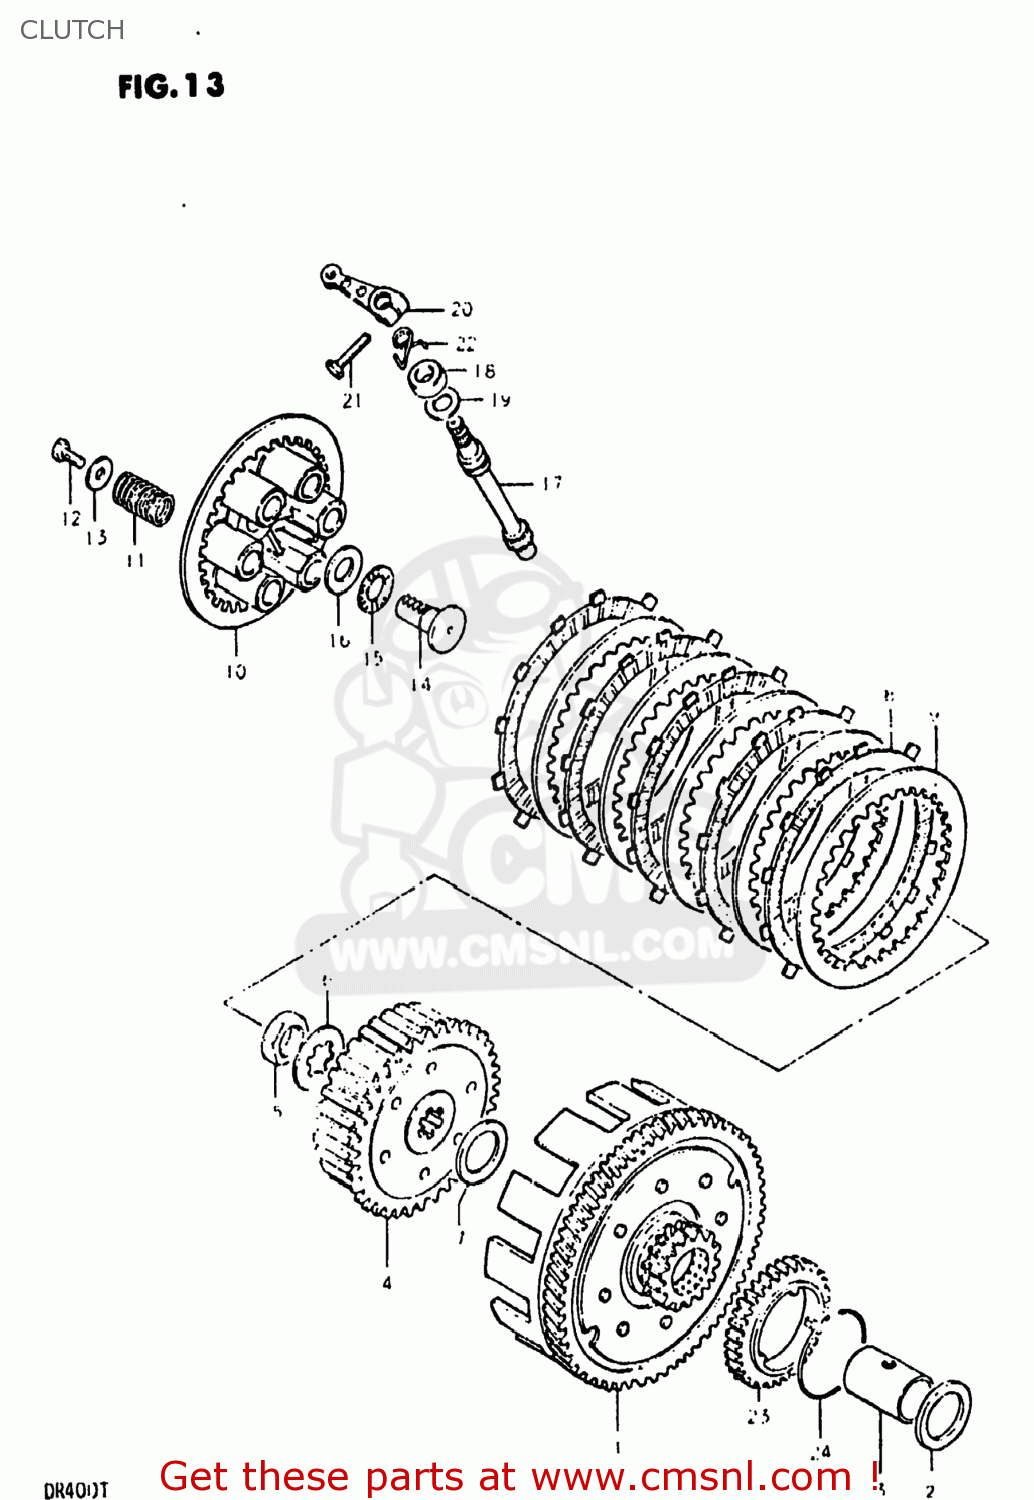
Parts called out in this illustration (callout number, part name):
1	GEAR ASSEMBLY,PRIMARY DRIVE
2	WASHER
3	SPACER
4	HUB,CLUTCH SLEEVE
5	NUT (20MM)
6	WASHER,LOCK
7	WASHER(20X38X2)
8	PLATE,CLUTCH DRIVE (MCA)
9	PLATE,CLUTCH DRIVEN (NAS)
10	DISC,CLUTCH PRESSURE
11	SPRING
12	BOLT, UPPER
13	WASHER
14	RACK,CLUTCH RELEASE
15	BEARING(15X28X2)
16	WASHER
17	PINION,CLUTCH RELEASE
18	OIL SEAL
19	WASHER (14.2X22X1)
20	ARM,CLUTCH RELEASE
21	BOLT,REAR
22	SPRING
23	GEAR,OIL PUMP DRIVE
24	CIRCLIP
